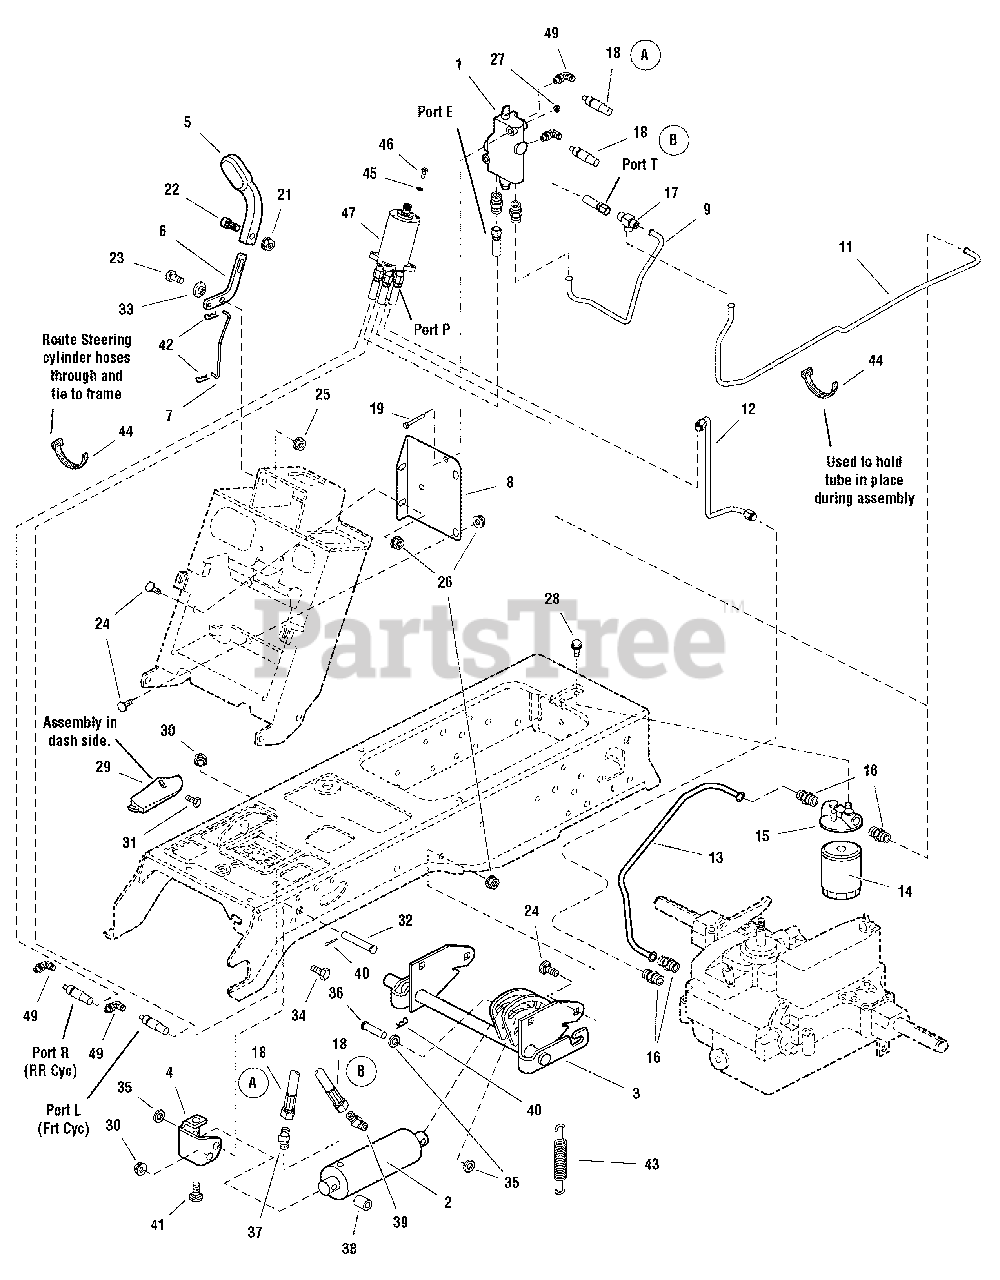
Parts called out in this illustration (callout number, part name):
1	VALVE, Control
2	CYLINDER, Hydraulic
3	SHAFT ASSEMBLY, Lift
4	SUPPORT, Cylinder
5	HANDLE, Lift
6	LEVER, Hydraulic
7	ROD, Curved Link
8	SUPPORT, Control
9	TUBE, Hydraulic
11	TUBE, Hydraulic
12	TUBE, Hydraulic 3 Bends
13	TUBE, Hydraulic
14	FILTER, Oil
15	BASE, Oil Filter
16	FITTING, Straight
17	FITTING, Tee, 3 Ports / Hydraulic Hose
18	HOSE ASSEMBLY, Hydraulic
19	CAPSCREW, Hex Head, 1/4-20 x 2 G5
20	SHAFT ASSEMBLY, Lift
21	NUT, Hex Lock ESNA Light 1/4-20
22	SCREW, Torx Plus Socket Head 1/4-20 x 7/8
23	CAPSCREW, Hex Head 5/16-18 x 1 G5
24	CARRIAGE BOLT, 5/16-18 x 3/4 G5
25	NUT, Hex Lock ESNA Light, 5/16-18
26	NUT, Hex KEPS 5/16-18
27	NUT, Hex KEPS 1/4-20
28	SCREW, Hex Whiz Lock Flange, 1/4-20 x 1/2
29	COVER, Dash ABS
30	NUT, Hex KEPS 3/8-16
31	SCREW, Pan Head Torque, #8-16 x 1/2, Plastite
32	PIN, Clevis
33	SPACER, Hydraulic Lift Pivot
34	CAPSCREW, Hex Head 3/8-16 x 1 G5
35	WASHER, 1/2
36	PIN, Flat Head Drilled
37	FITTING, Elbow 1/2
38	SPACER
39	FITTING, Elbow 1/2
40	CLIP, Hair Pin
41	CARRIAGE BOLT, 3/8-16 x 1 G5
42	PIN, Cotter 5/8 x 3/4
43	SPRING
44	TIE, Self Locking
45	LOCKWASHER, Spring 1/4
46	CAPSCREW, Hex Head
47	POWER STEERING UNIT, w/Hoses
49	FITTING, Hose Elbow Perma Push 9/16-18
